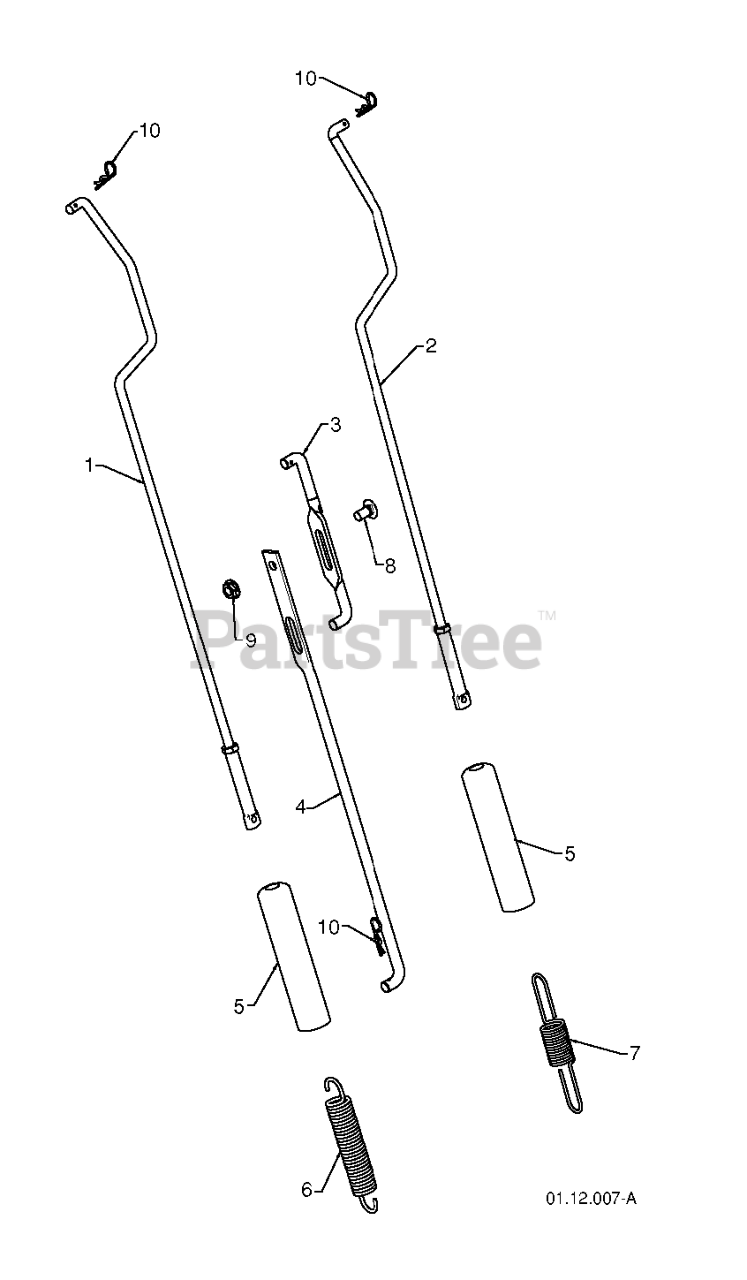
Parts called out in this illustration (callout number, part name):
1	ROD.ASM.IMPELLER
2	ROD.ASM.TRACTION.HYD.CLUTCH
3	ROD.SHIFTER.TOP.HYD
4	ROD, LOWER, SPEED CONTROL
5	SLEEVE, SPRING
6	SPRING, AUGER CONTROL
7	SPRING, TRACTION DRIVE
8	BOLT
9	NUT.FLANGE.5/16
10	SPRING RETAINER
